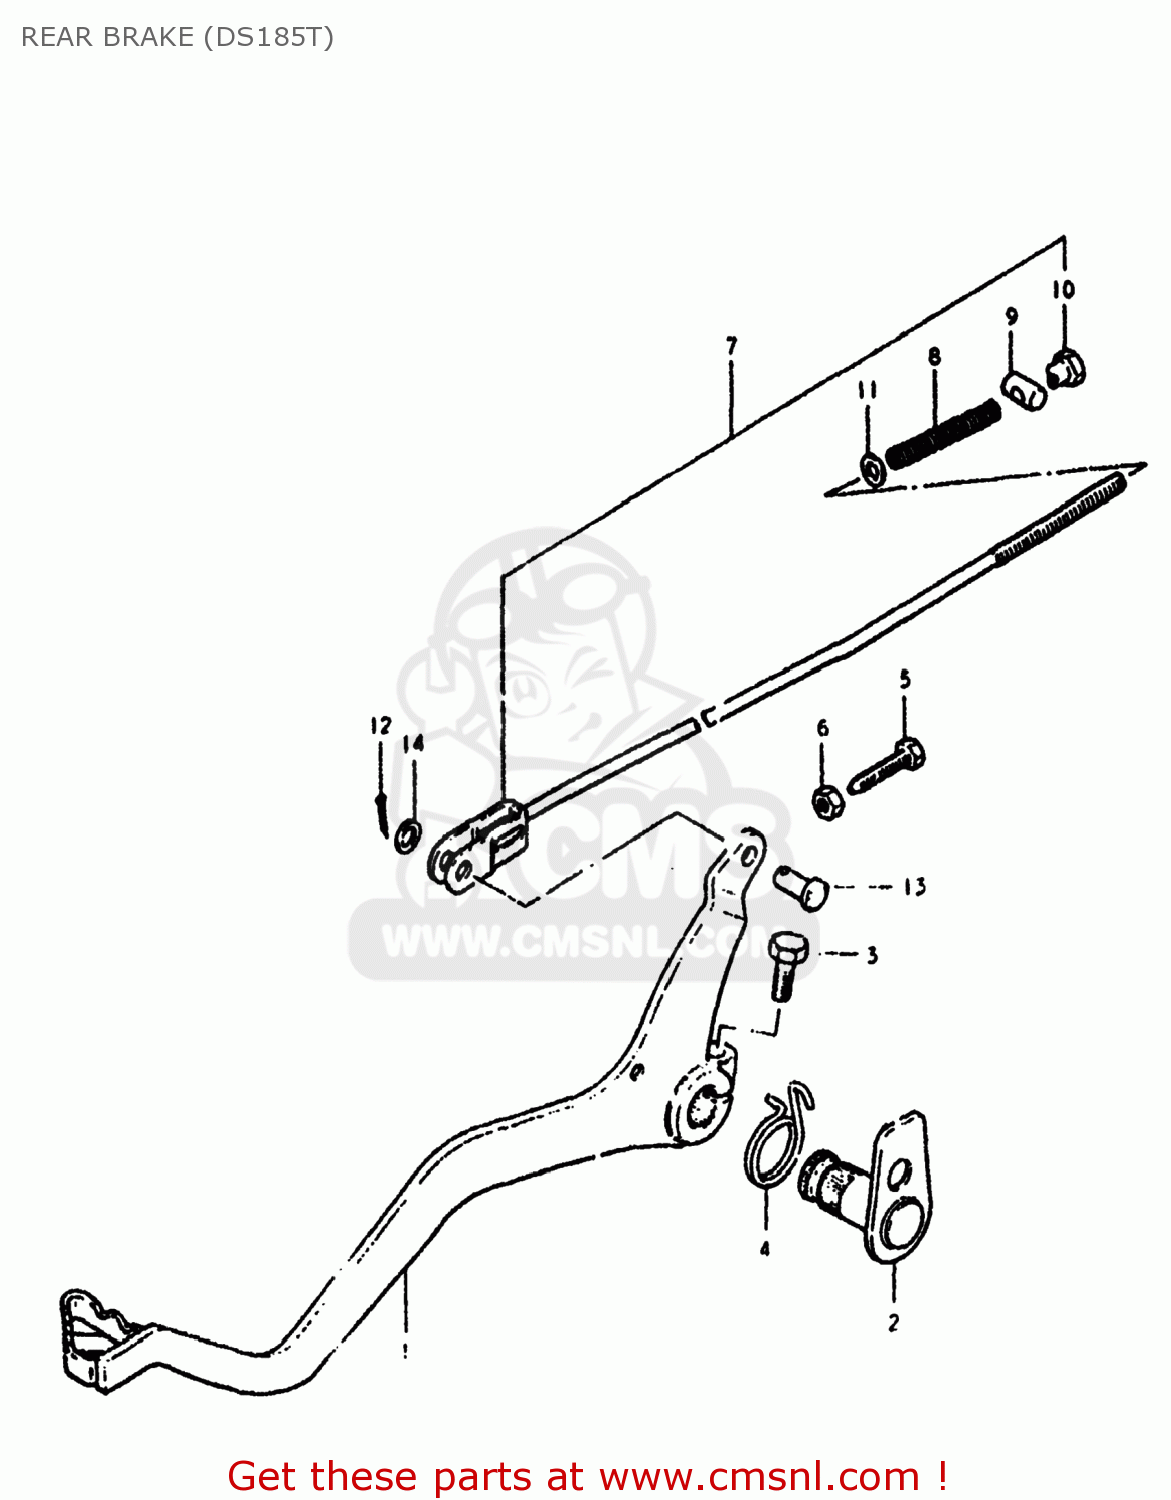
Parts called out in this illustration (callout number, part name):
1	PEDAL,BRAKE
2	ARM,BRAKE PEDAL
3	BOLT
4	SPRING
5	BOLT(6X23)
6	NUT
7	ROD ASSY,RR BRAKE
8	SPRING
9	PIN
10	NUT
11	WASHER
12	PIN 20X20
13	PIN(L:13.5)
14	WASHER
